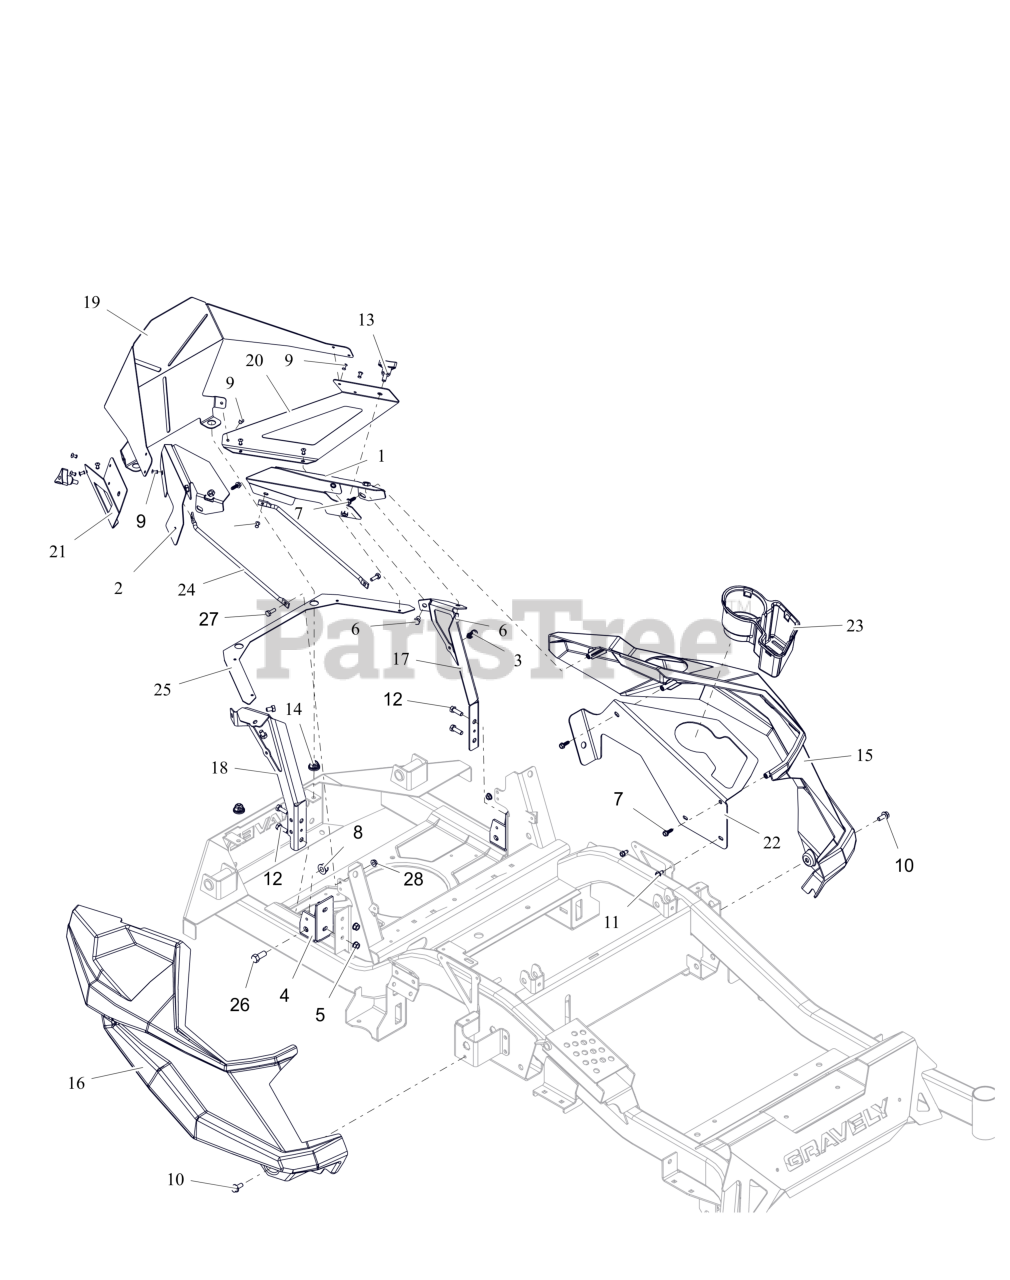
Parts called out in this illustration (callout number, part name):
1	PANEL, LH (RED)
2	PANEL, RH (RED)
3	CLIP, CABLE GUIDE
4	BRKT, ROPS SUPPORT
5	NUT,LK-CTR-FLG .31-18 GF ZCC
6	BLT, HEX .31-18X.50 GR5 ZCC
7	SCR, PLASTITE-HWH 0.25 X 0.75 ZC120
8	NUT,NYL-FLG .44-14 GF ZCC
9	RIVET, #66 STEEL POP PD BLACK
10	BLT, SERHFWH 0.312-18X0.75 GR5 ZCC
11	SCR-TAP .25-20X.50 HWH ZCC
12	BLT, HEX .31-18X1.00 G8 ZCC
13	KNOB,WING STUD 5/16-18 X .75
14	GROMMET, 10MM BOLLHOFF
15	FENDER, LH
16	FENDER, RH
17	BRKT, LH FENDER MTG (RED)
18	BRKT, RH FENDER MTG (RED)
19	WRAP, REAR (BLACK)
20	WRAP, REAR - LH (RED)
21	WRAP, REAR - RH (RED)
22	PANEL, HD CUPHOLDER (RED)
23	HOLDER, CUP
24	ROD, STIFFENER
25	STIFFENER, BACK WRAP (RED)
26	BLT, HEX 0.4375-14X1 GR5 ZCC
27	BLT, HEX .25-20X.75 G5 ZCC
28	NUT-LK-CTR-FLG .25-20 ZC120
